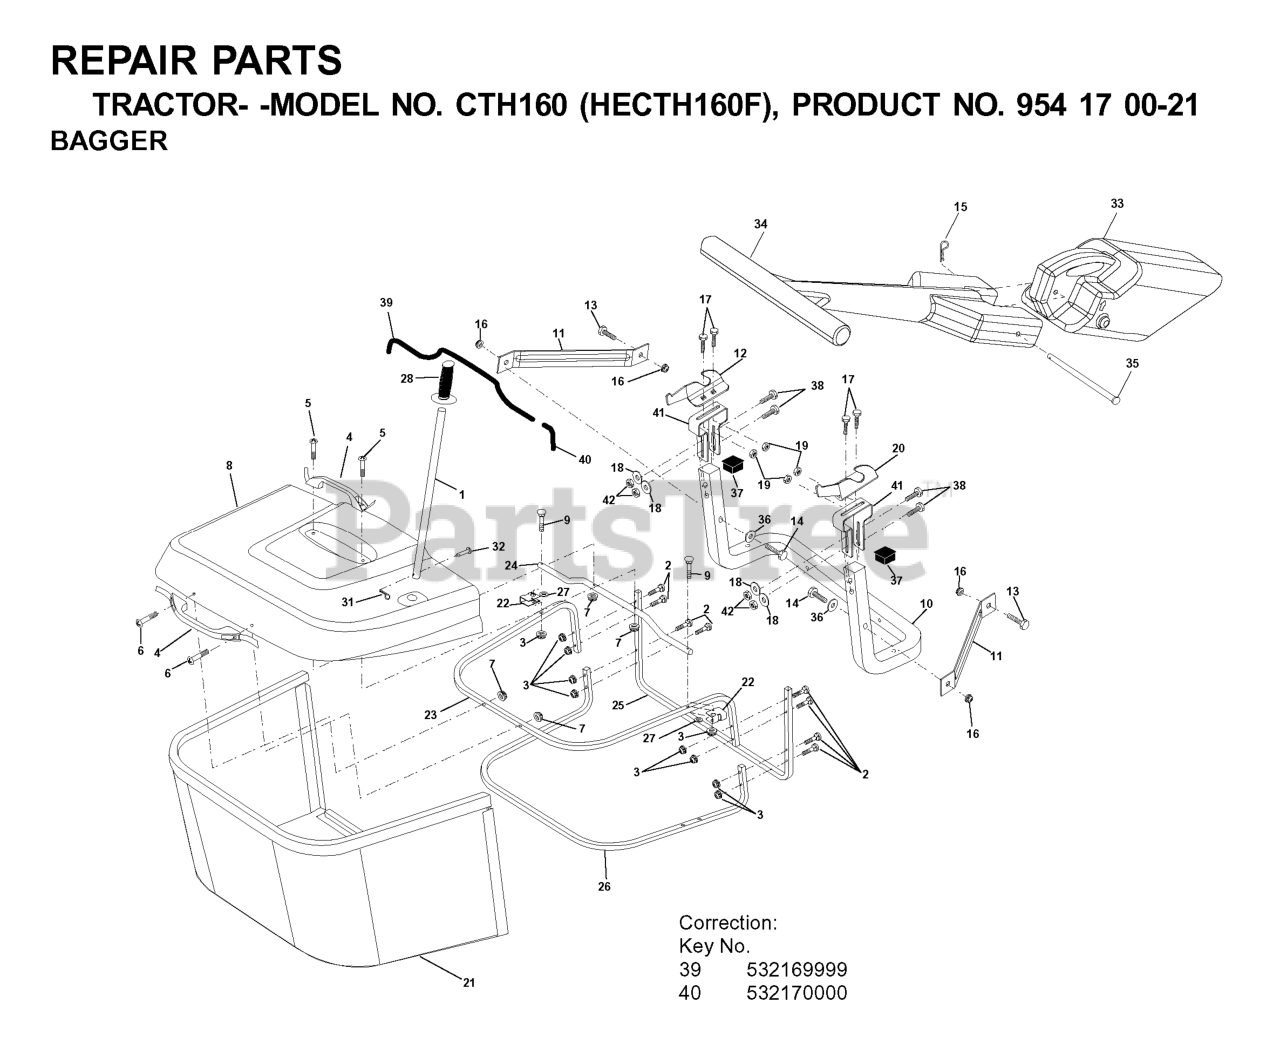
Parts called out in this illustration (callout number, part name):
1	TUBE HANDLE BAGGER
2	Bolt Carriage 1/4-20 x 2.0 Gr.5
3	NUT T
4	HANDLE.BAGGER.W/LVRS.BLK.CRD
5	SCREW.PAN.HEAD
6	REPL BY 532 75 00-29
8	COVER
9	Bolt Carriage 1/4-20 x 2.25d x Gr.5
10	TUBE
11	BRACKET.SUPPORT.UPPER.BAG.CRD
14	Bolt Hex 3/8-16 x 2-1/2 Gr. 5
15	RETAINER-SPRNG RB
16	NUT LOCK FLG 3/8-16 UNC
17	RP BOLT 5/16-18 X3/4 ZN/YEL GR
18	WASHER M
19	NUT LOCK HEX FLANGE 5/16-18
20	BRACKET
21	BAG
22	BRKT.SIDE.BAG.CRD
23	TUBE.UPPER.BAG.CRD
24	TUBE.PIVOT.BAG.CRD.BLACK
26	TUBE.LOWER.BAG.CRD
28	Grip Handle Black
31	RETAINER M
32	RIVET,DRILLED
33	MULCH PLUG, CTH150
34	HANDLE.MULCHER.92.CRD (2 2)
36	WASHER
37	Plug Support Bagger CRD
38	BOLT.5/16-18X2.5
41	BRKT.VERT.ADJ.BAGGER.CRD
42	NUT.71038.31-18.HEX.NYLOCK
